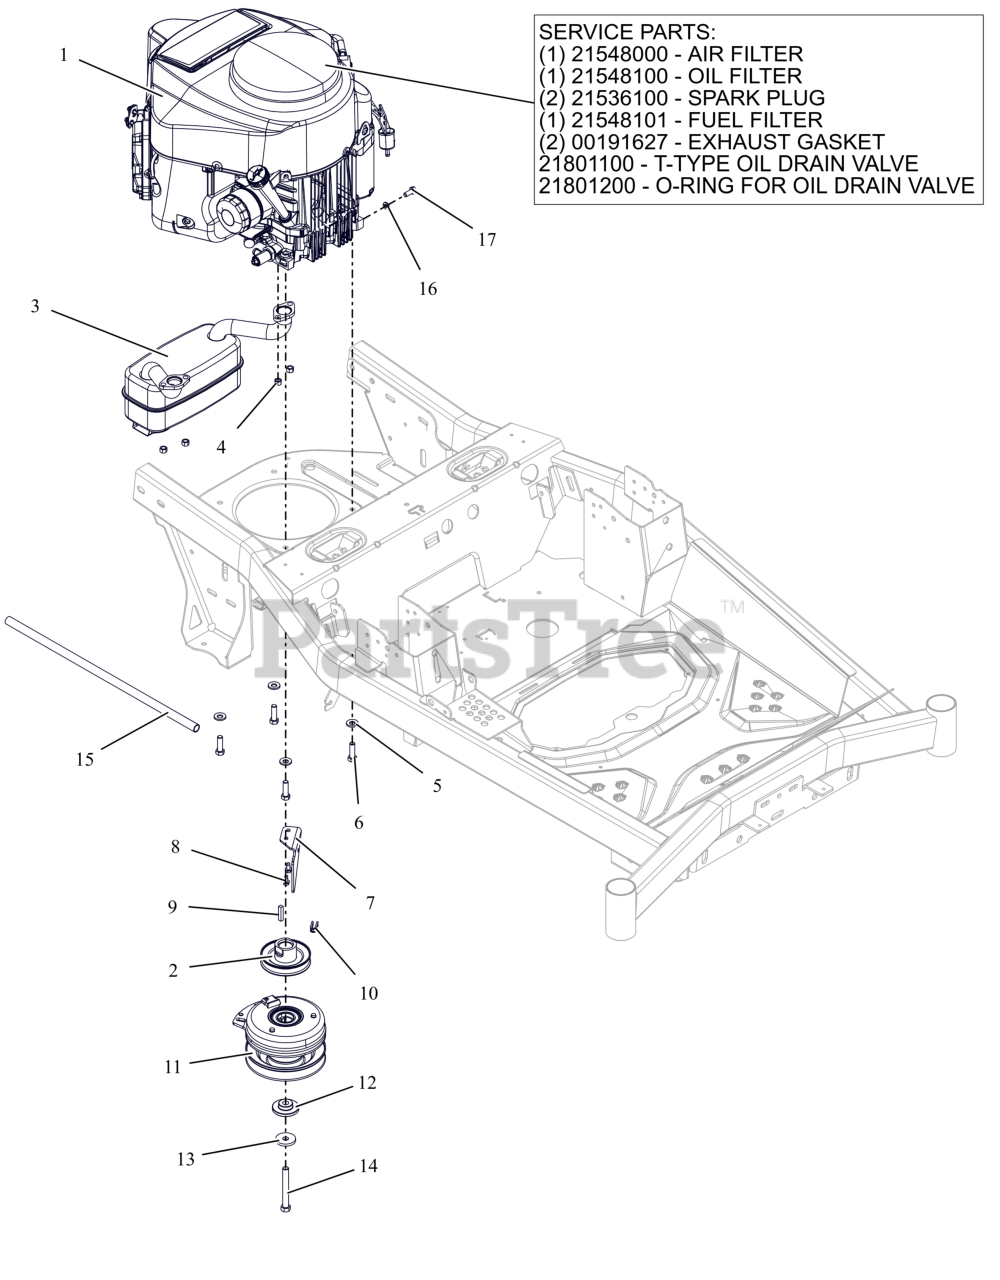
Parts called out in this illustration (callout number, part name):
1	ENGINE, KAWASAKI FR691 23HP
1	AIR FILTER, KAWASAKI FR
1	OIL FILTER, KAWASAKI FR
1	PLUG, SPARK
1	FUEL FILTER-KAWASAKI FR
1	GASKET, MUFFLER S/O
1	VALVE- T-TYPE OIL DRAIN
1	O-RING- OIL DRAIN VALVE
2	WLDMT-PULLEY-4.831OD X1.003
3	MUFFLER - KAWASAKI
4	NUT-LK-TOP-FLG M8 ZCC
5	WASHER, 3/8" SPRING DISC
6	BLT, HEX .38-16X1.25 G5 ZCC NT
7	BRKT- CLUTCH STOP
8	SCR-TAP .25-20X.50 HWH ZCC
9	KEY-SQ .25 X 1.25 X .25 SAE
10	BSHG, CLUTCH
11	CLUTCH, WARNER-IXR-18211
12	BSHG-FLG .469X1.06X.574X2.0
13	WASHER, 7/16" SPRING DISK
14	BLT- HEX .44-20X3.50 G8 ZCC NT
15	HOSE- OIL DRAIN
16	WSHR,LK-REG .312X.078 ZCC
17	BLT, HEX M8-1.25X20 G8.8 ZCC
